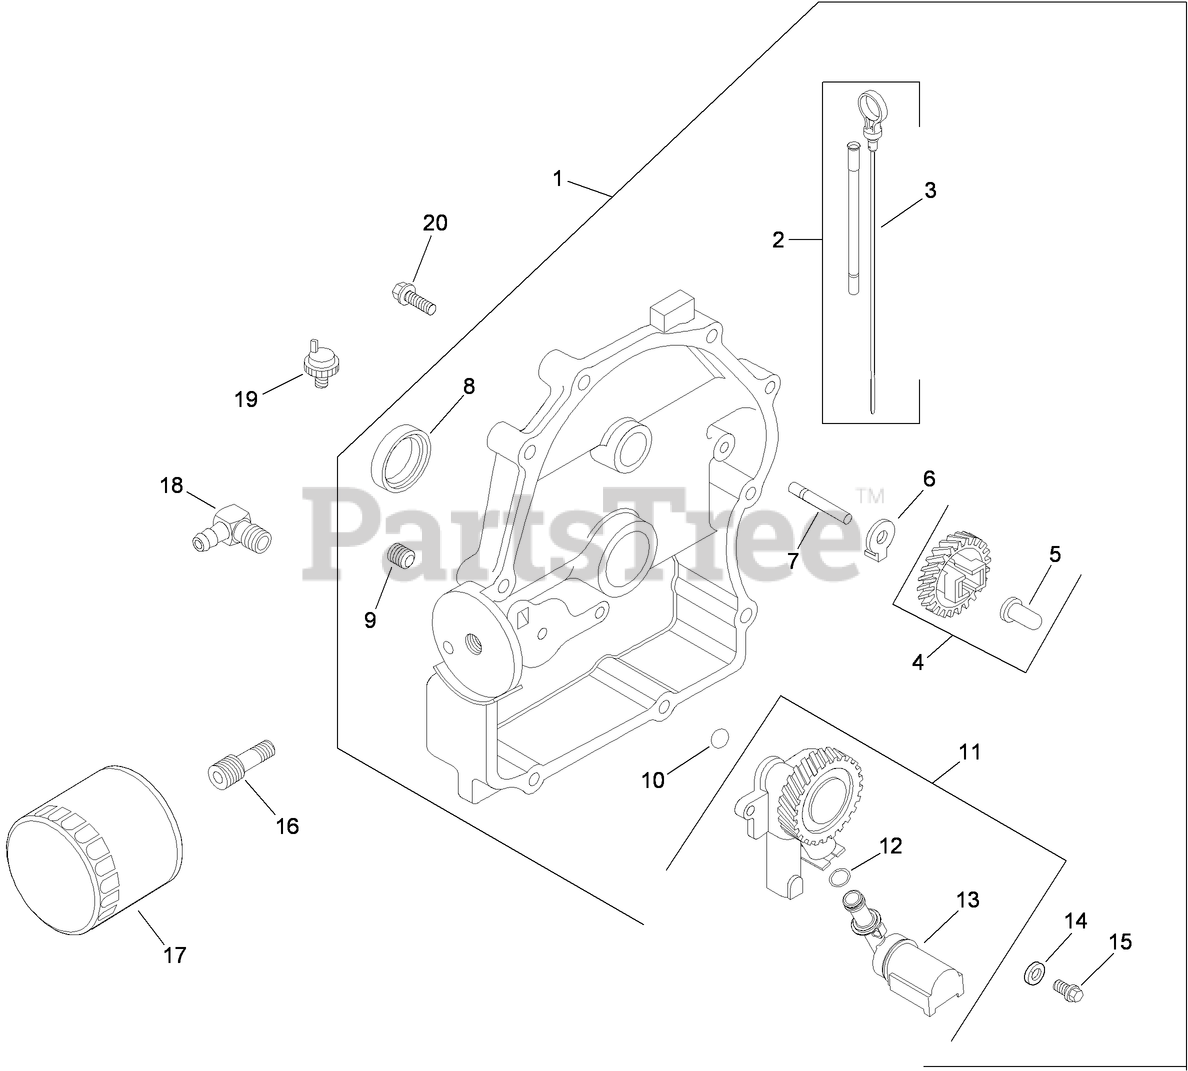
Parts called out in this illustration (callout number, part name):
1	Closure Plate ASM (Includes 2-15)
2	Dipstick Tube ASM (Includes 3)
3	Dipstick
4	Governor Gear Kit (Includes 5)
5	PIN-REGULATING, GOVERNOR
6	TAB-LOCKING
7	SHAFT-GEAR, GOVERNOR
8	Seal-Oil (PTO End)
9	PLUG-PIPE, COUNTERSUNK (1/8)
10	O-Ring
11	Oil Pump ASM (Includes 12, 13)
12	O-Ring (Oil Pick Up)
13	TUBE-PICK UP, OIL
14	WASHER-FLAT (6 MM)
15	SCREW-FLANGE, THREAD FORMING (M6X1.0X25)
16	Nipple-Filter, Oil
17	Filter-Oil
18	Connector-Hose, 90 Deg
19	SWITCH-PRESSURE, OIL
20	SCREW-FLANGE (M8X1.25X45)
